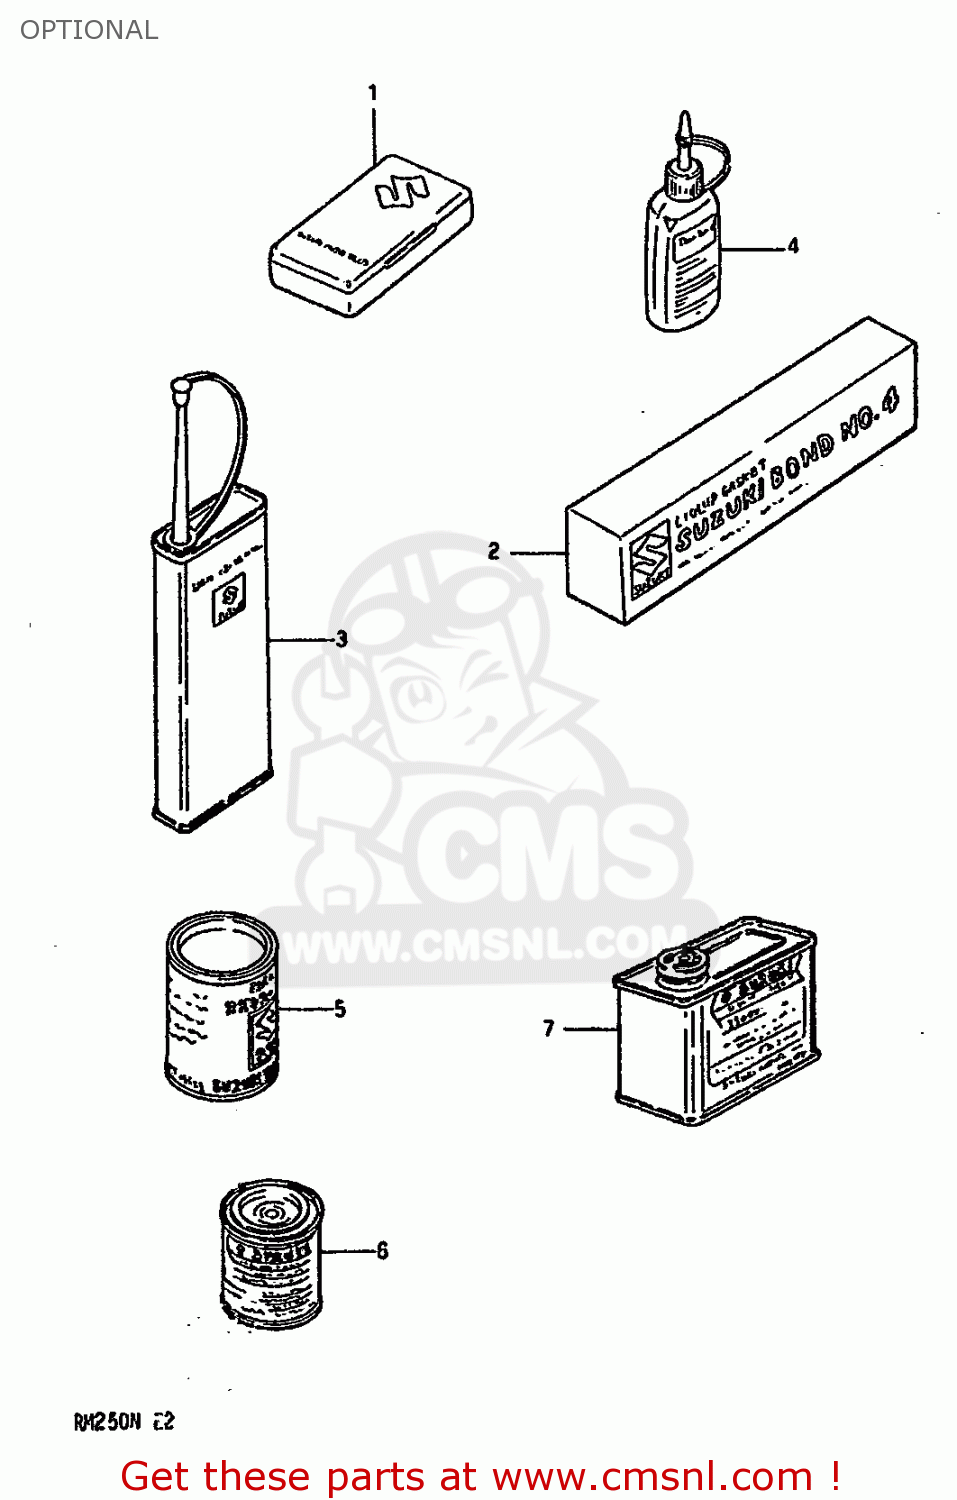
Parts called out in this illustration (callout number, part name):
1	TUBE REPARING TOOL
2	BOND 1104
3	THREAD LOCK NO.1401 CLEAR 200G
4	THREAD LOCK NO
5	GREASE(C)EP2 LITHIUM 150G
6	PAINT BLIGHT S
7	PAINT (CHAMPION BLUE)
